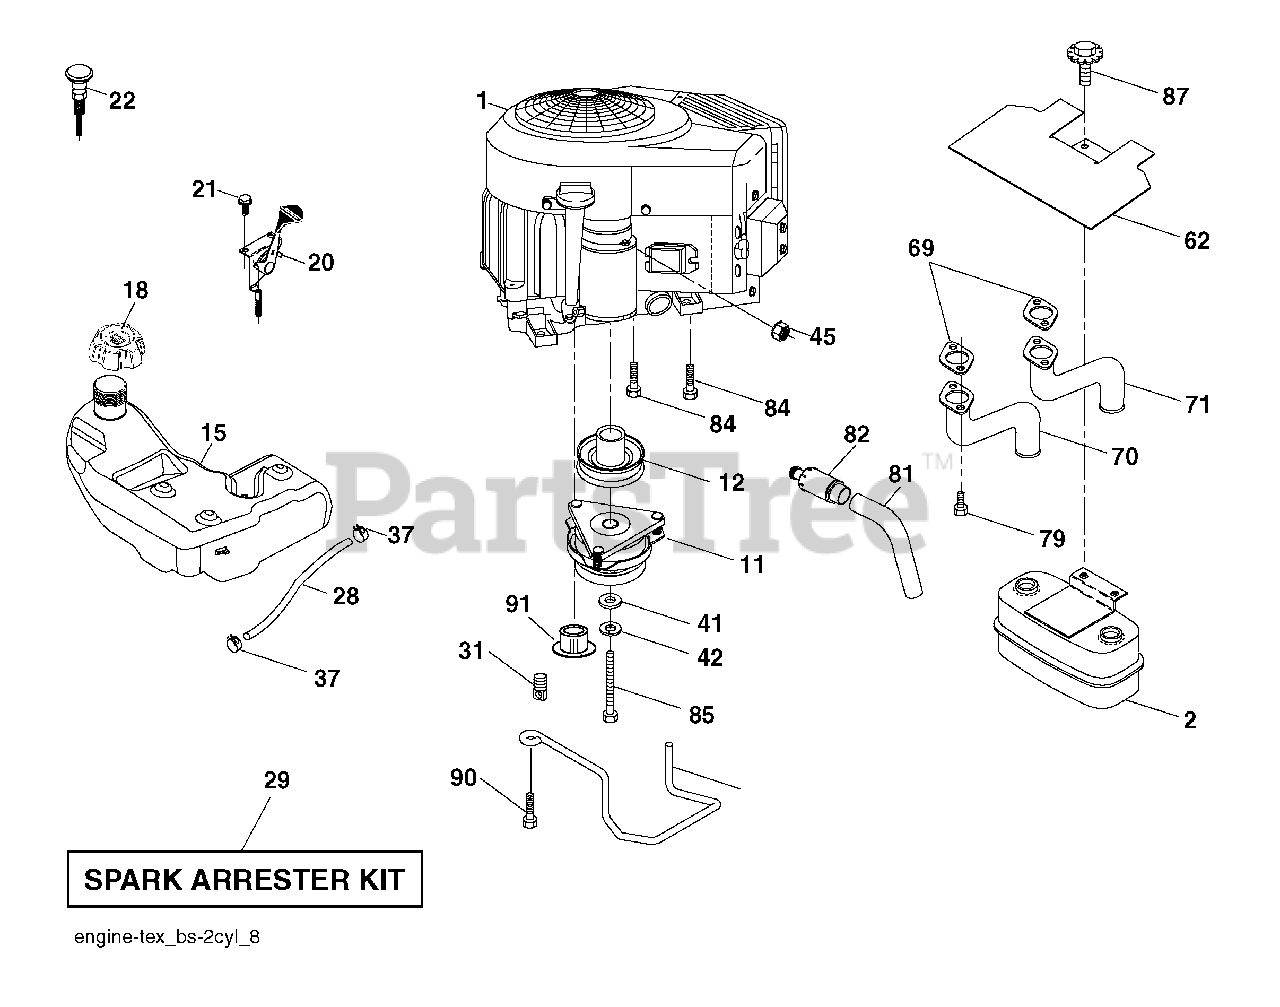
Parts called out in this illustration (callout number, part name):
2	Muffler
9	Keeper Belt Engine
11	Clutch Electric
12	Pulley Engine
15	Tank Fuel
18	Cap Asm.
20	Control Throttle
21	Screw #10 x 0.750 BOS Thread
22	Control Choke
28	Fuel Line
29	Spark Arrester Kit
31	Clip Push-In Hinged
37	Clamp Hose
41	Washer 1-1/2 OD x 15/32 ID x .250
42	Washer Lock 7/16
45	Nut Keps Hex 1/4-20 unc
62	Shield Heat Muffler
69	Gasket
70	Exhaust Tube LH
71	Exhaust Tube RH
79	Screw Socket Head 5/16-18 x 1
81	Tube Drain Oil Easy
82	Plug Drain Oil
84	Screw 3/8-16 x 1-1/4
85	Bolt Hex 7/16-20 x 3.75 Gr. 5
87	Bolt 5/16-18 x 1
90	Screw 3/8-16 x 1
91	Bushing 1.375 OD
